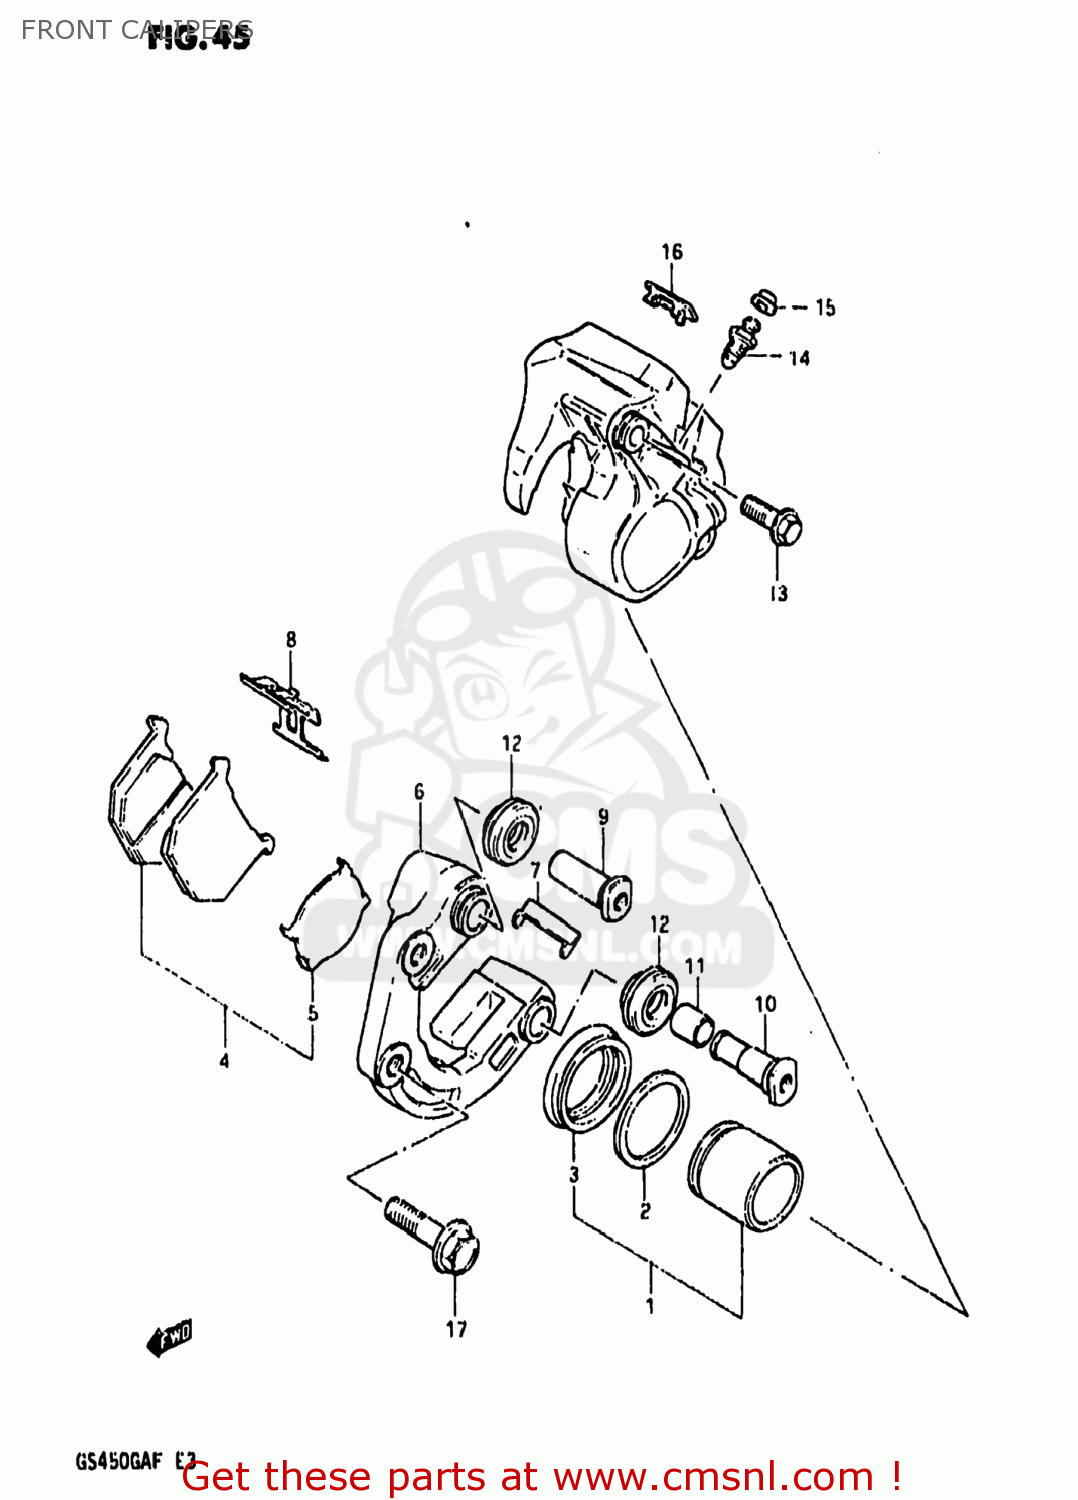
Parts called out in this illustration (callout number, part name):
1	PISTON SET
2	SEAL,FR CALIPE
3	BOOT,PISTON
4	PAD SET,BRAKE (MCA)
5	SHIM,PAD
6	CARRIER,CALIPER,LEFT
7	GUIDE,PAD
8	SPRING,PAD
9	AXLE NO.1
10	AXLE NO.2
11	BUSH,AXLE
12	BOOT,AXLE
13	BOLT
14	BLEEDER
15	CAP,BREATHER
16	COVER
17	BOLT(10X37)
